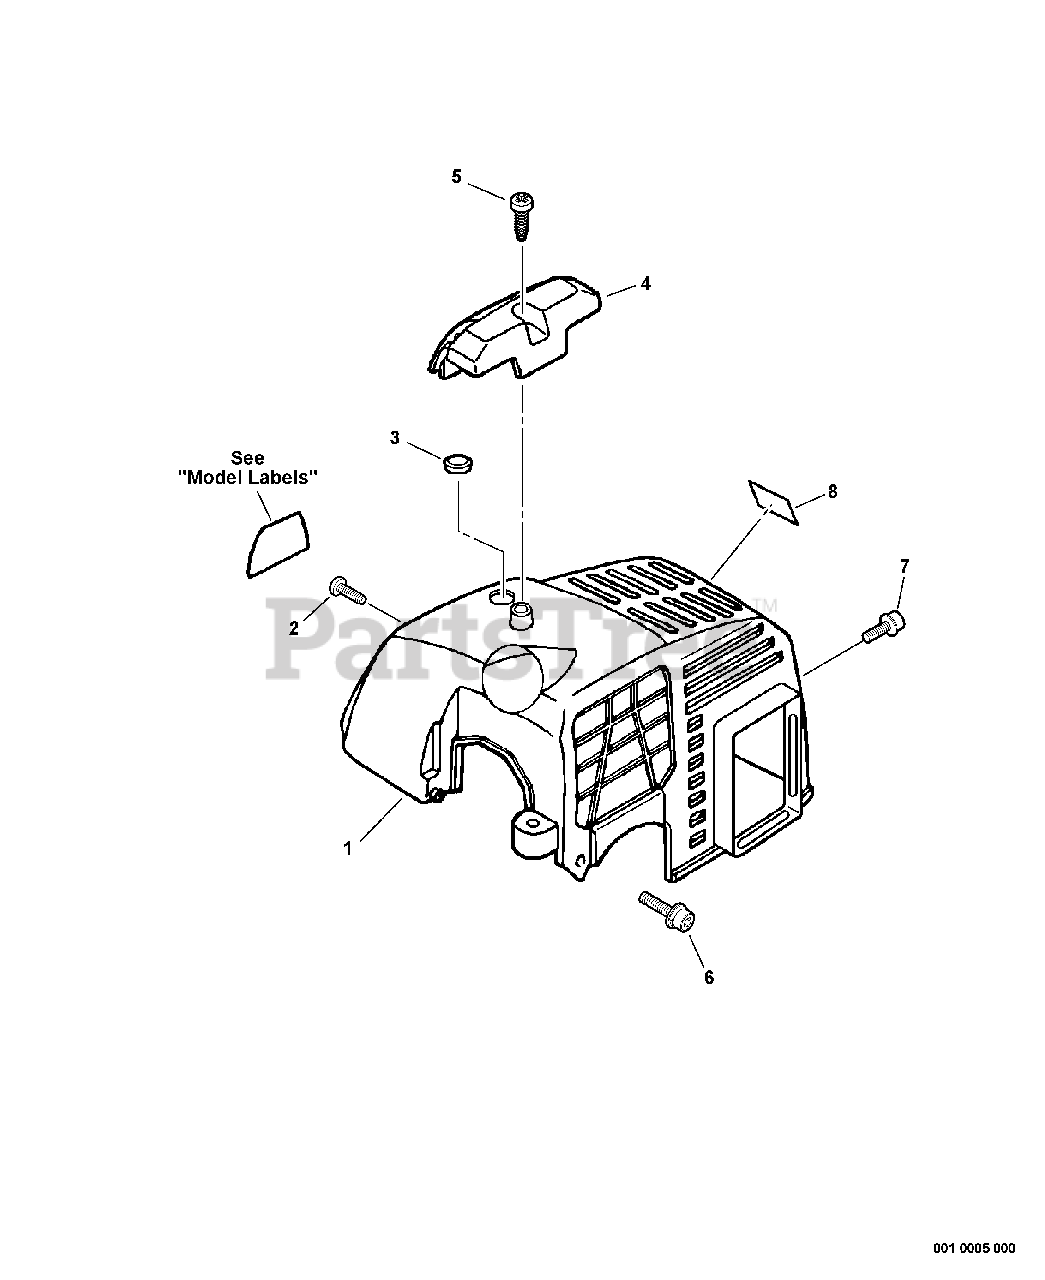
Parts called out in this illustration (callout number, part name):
1	COVER, ENGINE
2	SCREW - 4X12 -- TAPPING
4	GUARD - TOP
5	SCREW - 5X16 -- TAPPING
6	SCREW - 4X16
7	SCREW - 4X8
8	LABEL - HOT SURFACE
